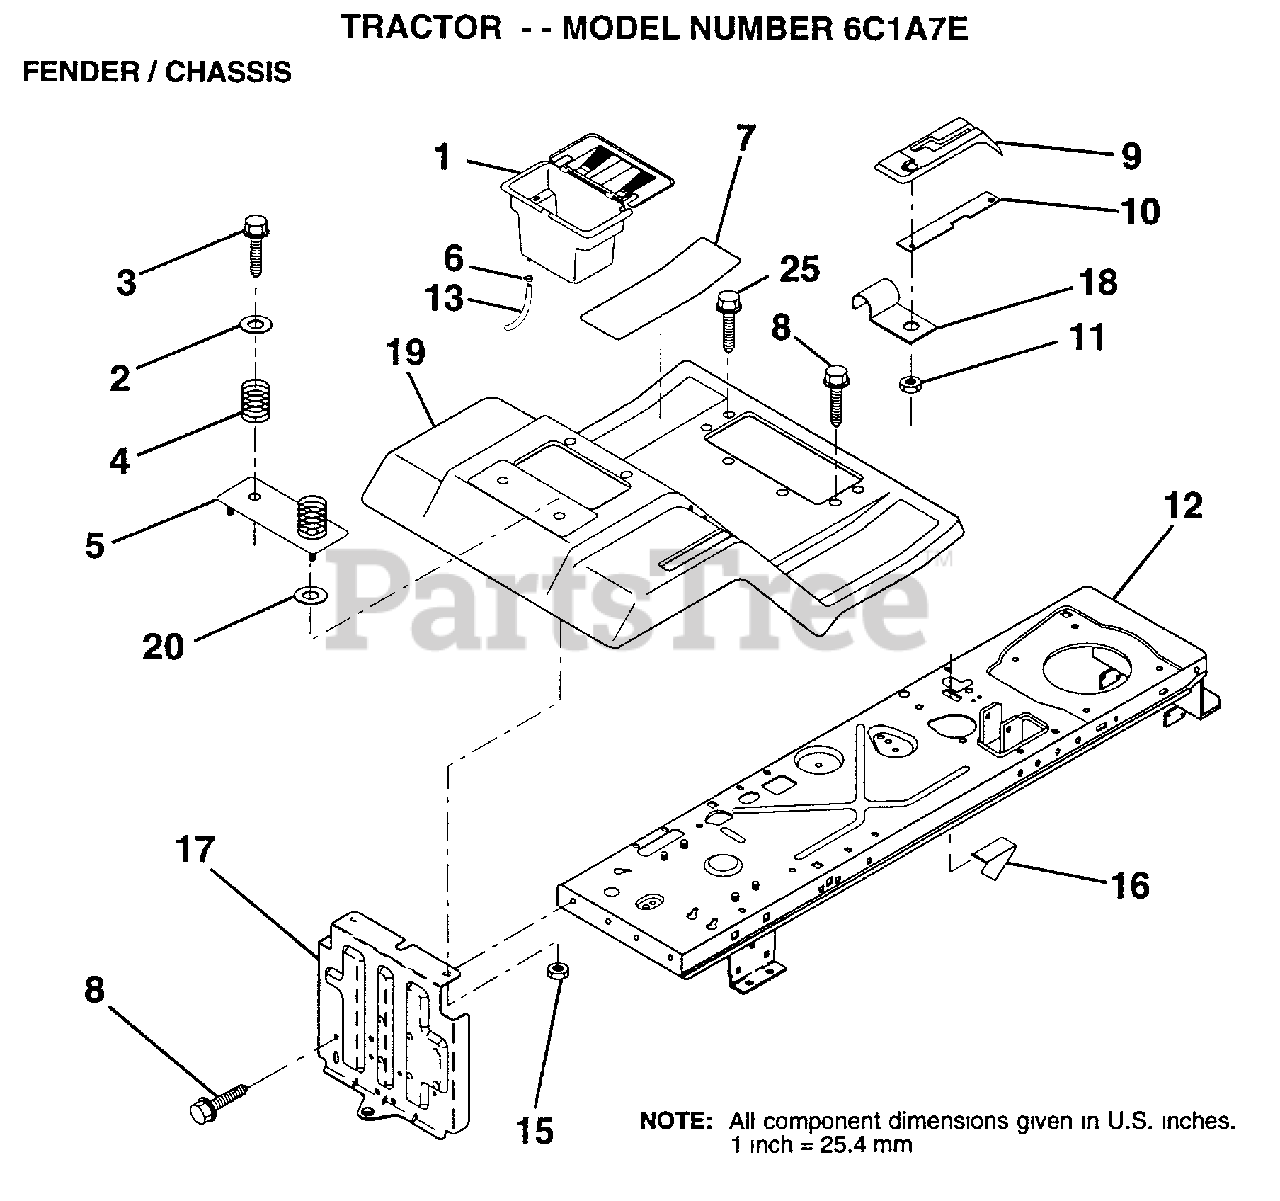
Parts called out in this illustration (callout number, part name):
2	WASHER
3	SCREW
4	SPRING COMPRESSIO
5	BTRY FENDER PLATE
6	HOSE CLAMP T
7	PAD FOOTREST
8	SCREW
9	CONSOLE SHFT 4SP
10	PLATE LOCK SHIFT
11	NUT
12	CHASSIS.WELD.ASM.
13	TUBE T
15	NUT HXKEP 1/4X20
17	DRAWBAR ASM LR
18	"CLIP,INSULATOR"
19	FENDER/FOOT MS505
25	SCREW
